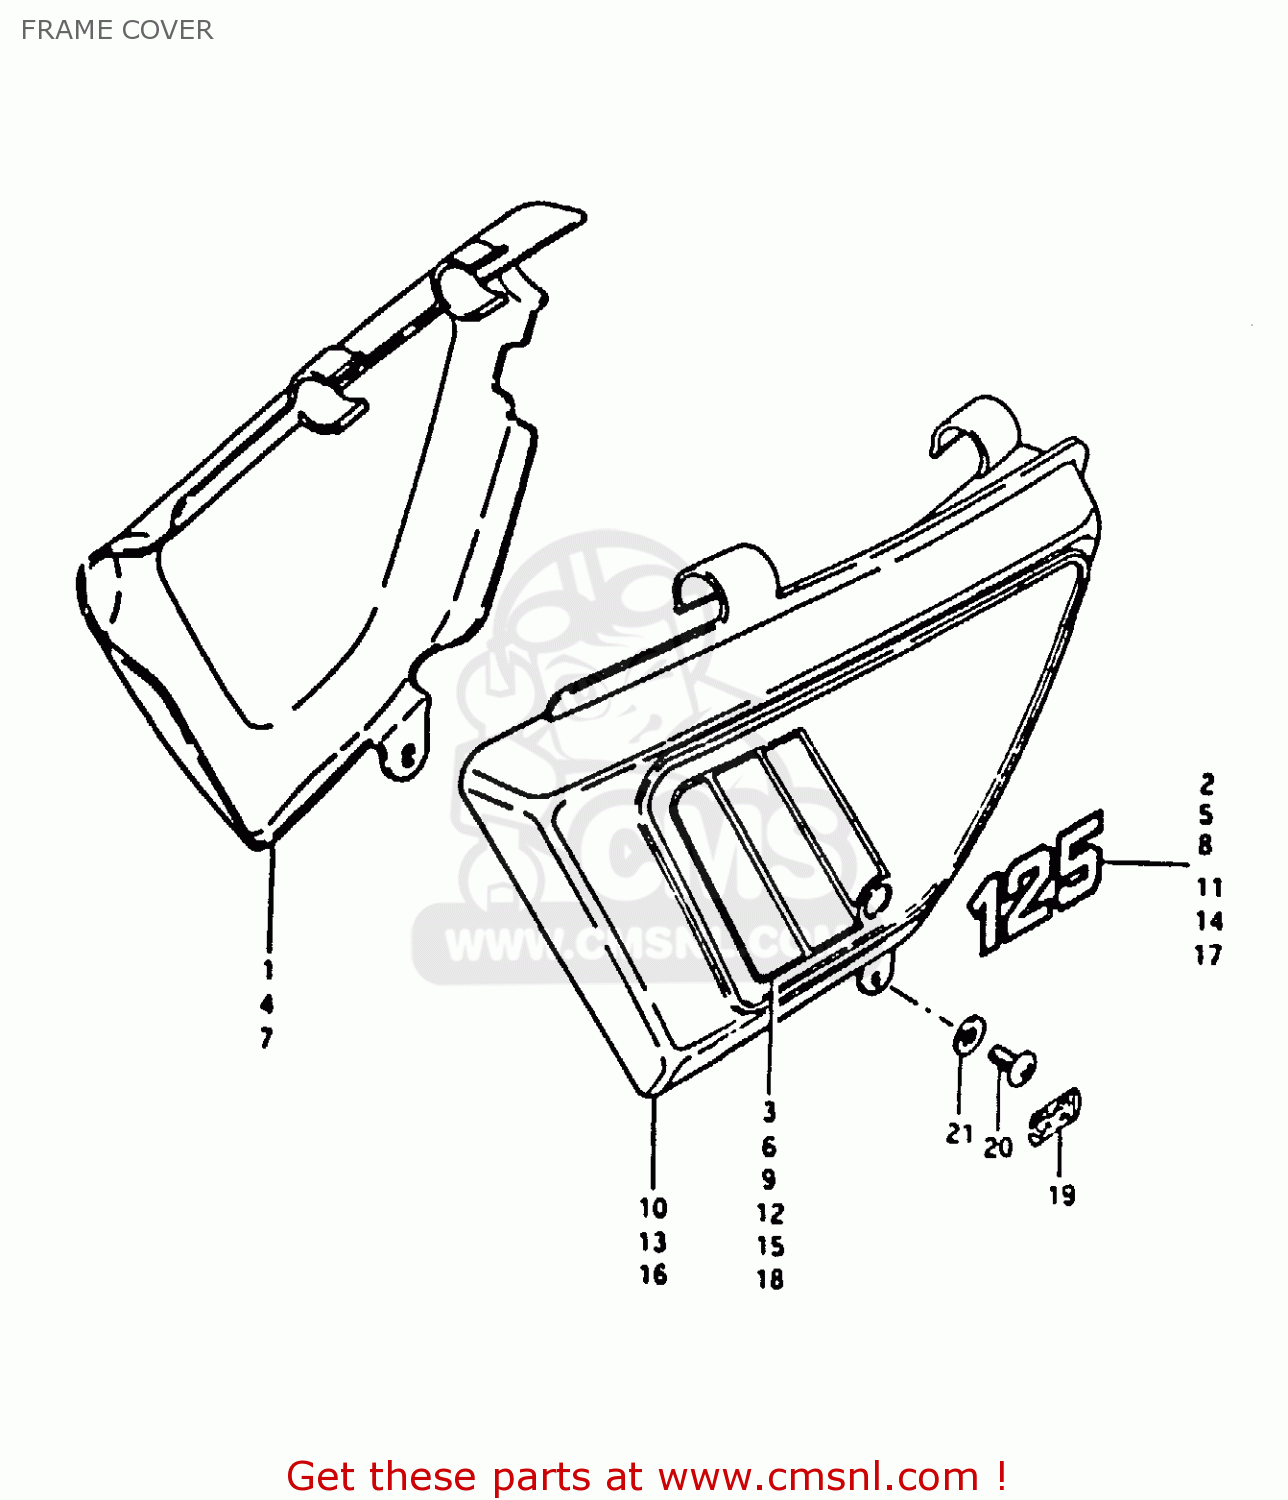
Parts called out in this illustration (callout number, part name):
1	COVER, FRAME RH (RED)
2	EMBLEM (WHITE)
3	TAPE, RH
4	COVER, FRAME RH (BLUE)
5	EMBLEM (WHITE)
6	TAPE, RH
7	COVER, FRAME RH (WHITE)
8	EMBLEM (BLACK)
9	TAPE, RH
10	COVER, FRAME LH (RED)
11	EMBLEM (WHITE)
12	TAPE, LH
13	COVER, FRAME LH (BLUE)
14	EMBLEM (WHITE)
15	TAPE, LH
16	COVER, FRAME LH (WHITE)
17	EMBLEM (BLACK)
18	TAPE, LH
19	EMBLEM,CCIS
20	SCREW 6X12
21	WASHER
